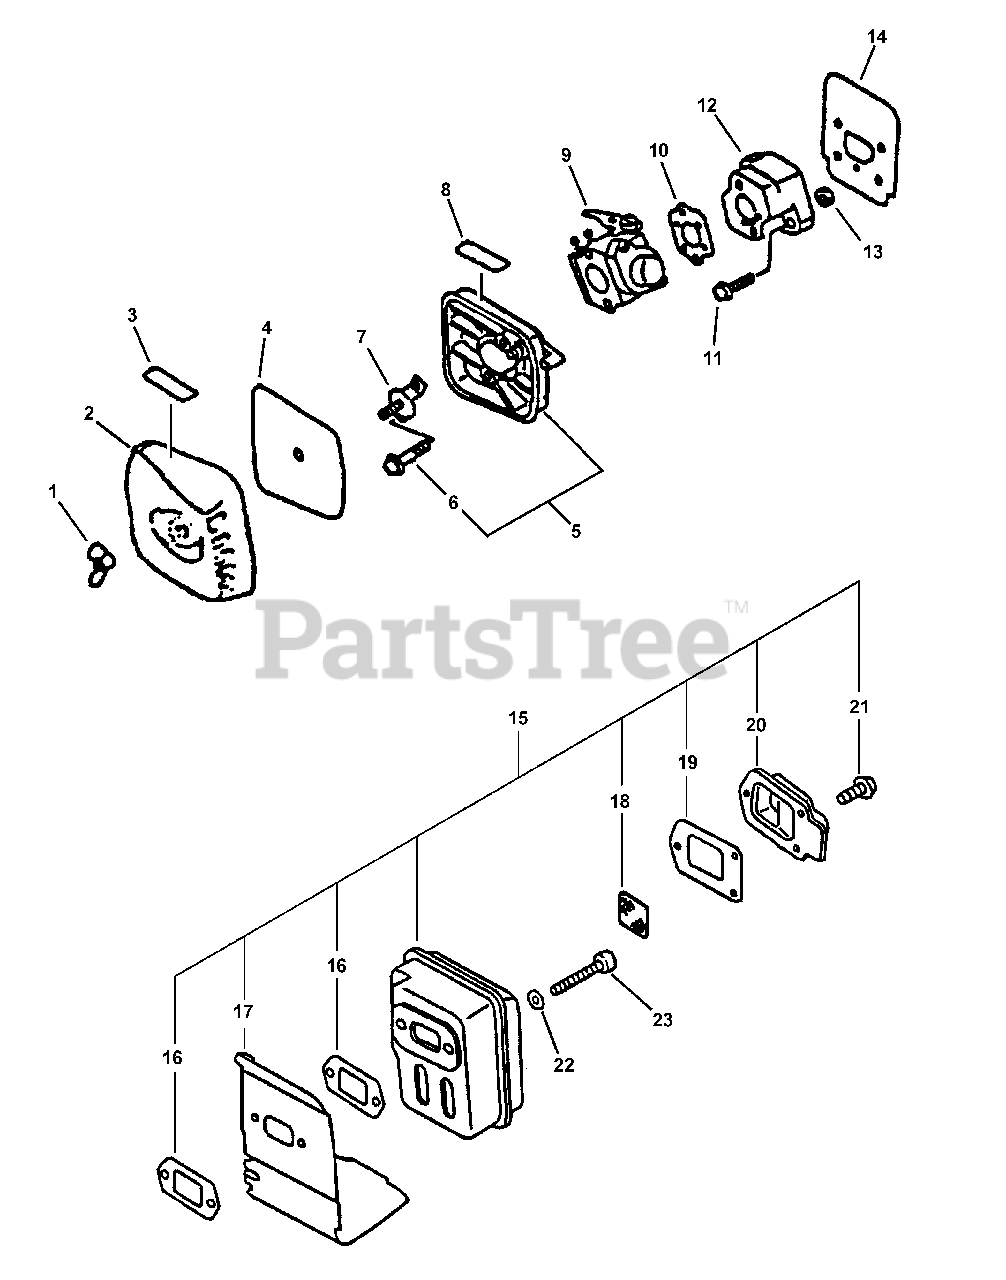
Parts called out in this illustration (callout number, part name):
1	WINGNUT - 6
2	COVER, AIR FILTER
3	LABEL - TOP
4	FILTER, AIR - SINGLE LAYER
5	AIR FILTER CASE ASSY
6	SCREW 5×65
7	PLATE, PREVENT
8	LABEL, CHOKE
9	CARBURETOR - C1U-K16
9	CARBURETOR - C1U-K47
9	CARBURETOR - C1U-K52
10	GASKET, INTAKE
11	SCREW 5×20
12	INSULATOR, INTAKE
13	NUT M5
14	HEAT SHIELD, INTAKE
15	MUFFLER ASSY
16	GASKET, EXHAUST
17	COVER, EXHAUST
18	SCREEN, SPARK ARRESTER
19	GASKET, EXHAUST
20	GUIDE, EXHAUST - INNER
21	SCREW 4×10
22	WASHER, FLAT 5.5×10×0.8
23	BOLT 5×55
